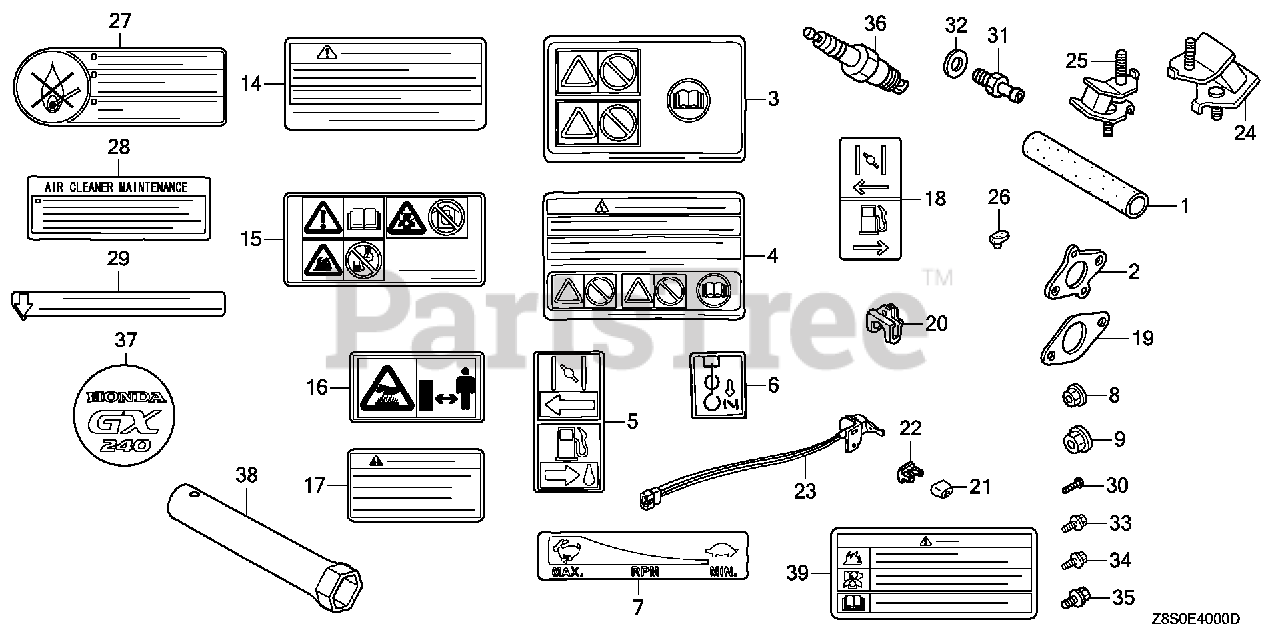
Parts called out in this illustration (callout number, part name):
3	MARK, OPERATOR CAUTION (PICTOGRAPH)(MADE IN JAPAN)
4	MARK, OPERATOR CAUTION (ENGLISH)(MADE IN THAI)
4	MARK, OPERATOR CAUTION (FRENCH)(MADE IN THAI)
5	MARK, CHOKE (GRAY)
7	MARK, THROTTLE INDICATION
